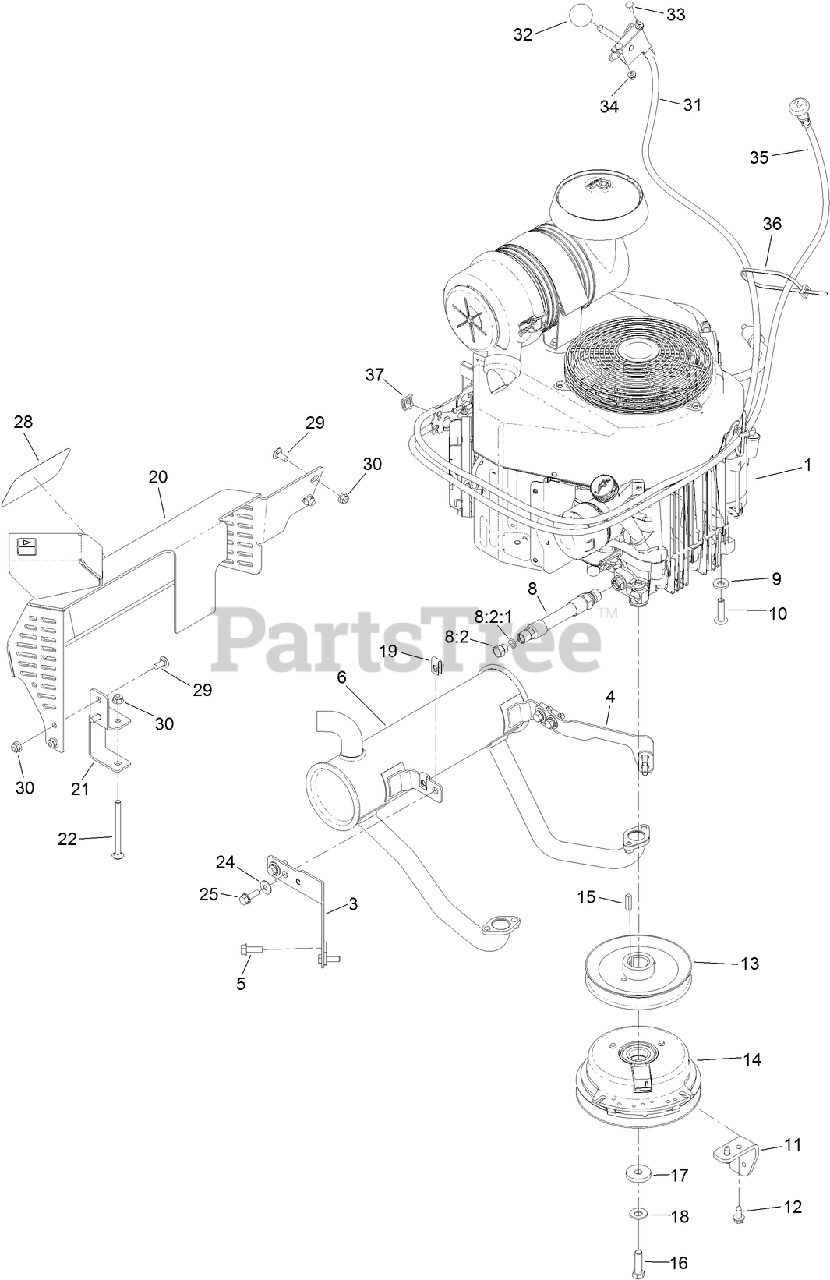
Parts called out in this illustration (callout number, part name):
1	ENGINE-KAWASAKI, FX691V
3	BRACKET-MUFFLER, FRONT
4	BRACKET-MUFFLER, REAR
5	SCREW-HHF
6	MUFFLER
8	HOSE ASM
8:2	PLUG-HH
8:2:1	O-RING
9	WASHER-BELLEVILLE
10	SCREW-BHTF
11	STOP-CLUTCH
12	SCREW-HWHTF
13	PULLEY
14	CLUTCH-200CMS
16	SCREW-HH
17	WASHER
18	WASHER-SPRING
19	NUT-U
20	MUFFLER GUARD ASM
21	BRACKET-MOUNTING, GUARD
22	SCREW-CARR
24	WASHER-BELLEVILLE
25	SCREW-HHF
28	DECAL
29	SCREW-CARR
30	NUT-HF, NI
31	THROTTLE ASM
32	KNOB-BALL
33	BOLT-CARR
34	NUT-LOCK, FLANGE
35	CABLE-CHOKE
36	TIE-CABLE
37	CLAMP-CABLE
